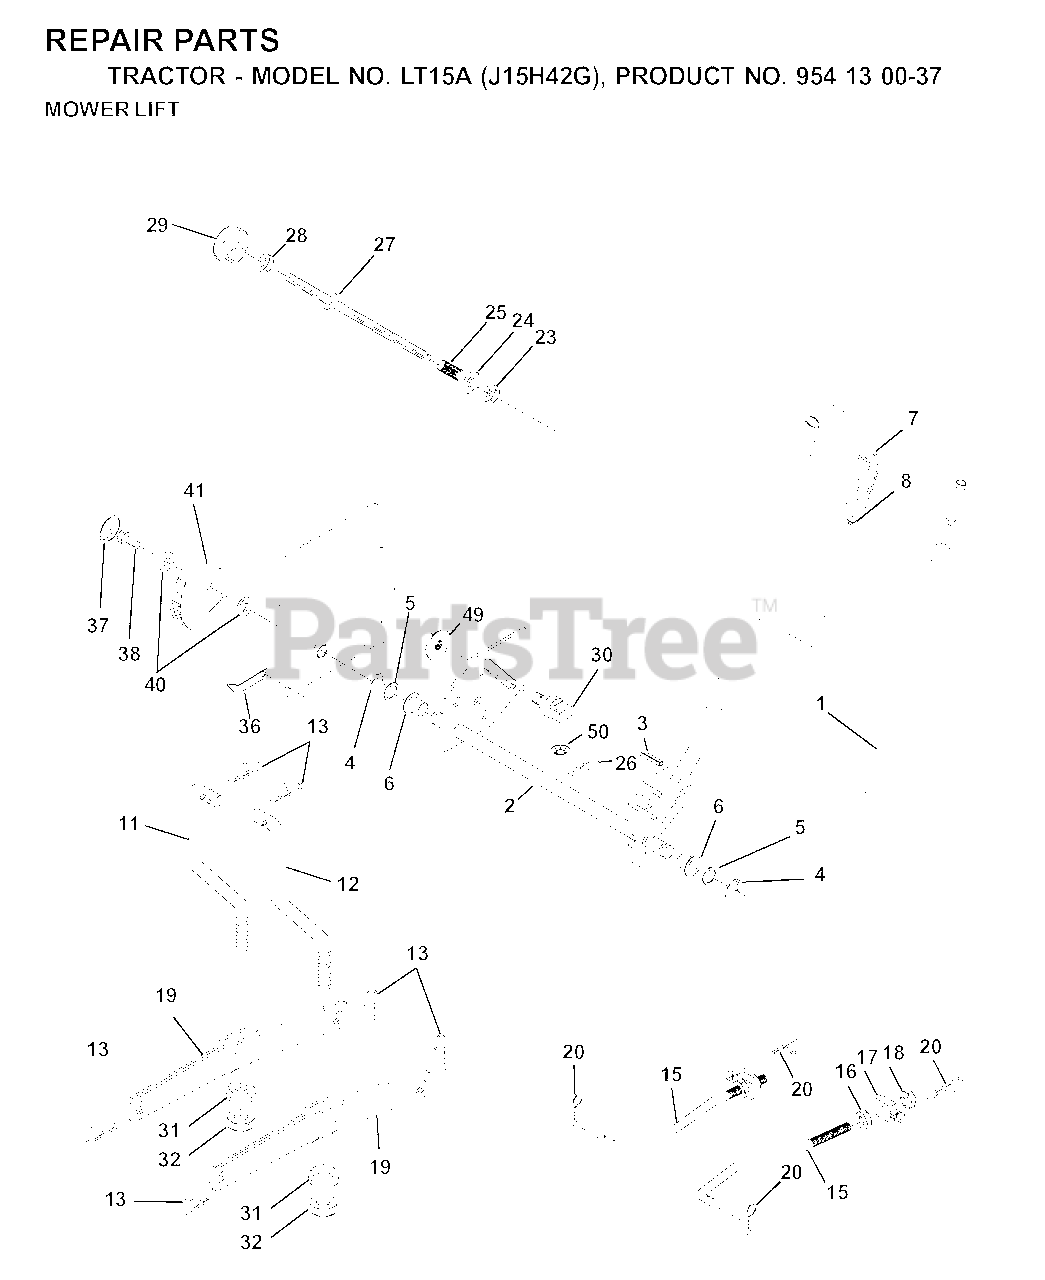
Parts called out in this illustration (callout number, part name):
1	WIRE ASM INNER W/ PLUNGER LT
2	SHAFT ASM R HANDLE
3	PIN GROOVE
4	RETAINING RING LT
6	BEARING.NYLON
7	GRIP HANDLE
11	LINK LIFT LH
12	LINK LIFT RH
13	RETAINER-SPRNG RB
15	LINK.SUSPENSION.FRONT
16	NUT
17	TRUNION
18	NUT
19	ARM.REAR.SUSPENSION
20	SPRING RETAINER
25	SPRING**
26	RETAINER CLIP
27	ROD ADJ LIFT
28	NUT
29	KNOB INF 3/8-16
31	BEARING PIVOT
32	NUT CROWNLOCK 3/8-24
36	POINTER, HEIGHT INDICATOR
37	PLUG,HOLE
38	SCREW 5/16-18X1
41	IND. HEIGHT STLT
49	NUT
50	NUT PUSH M
